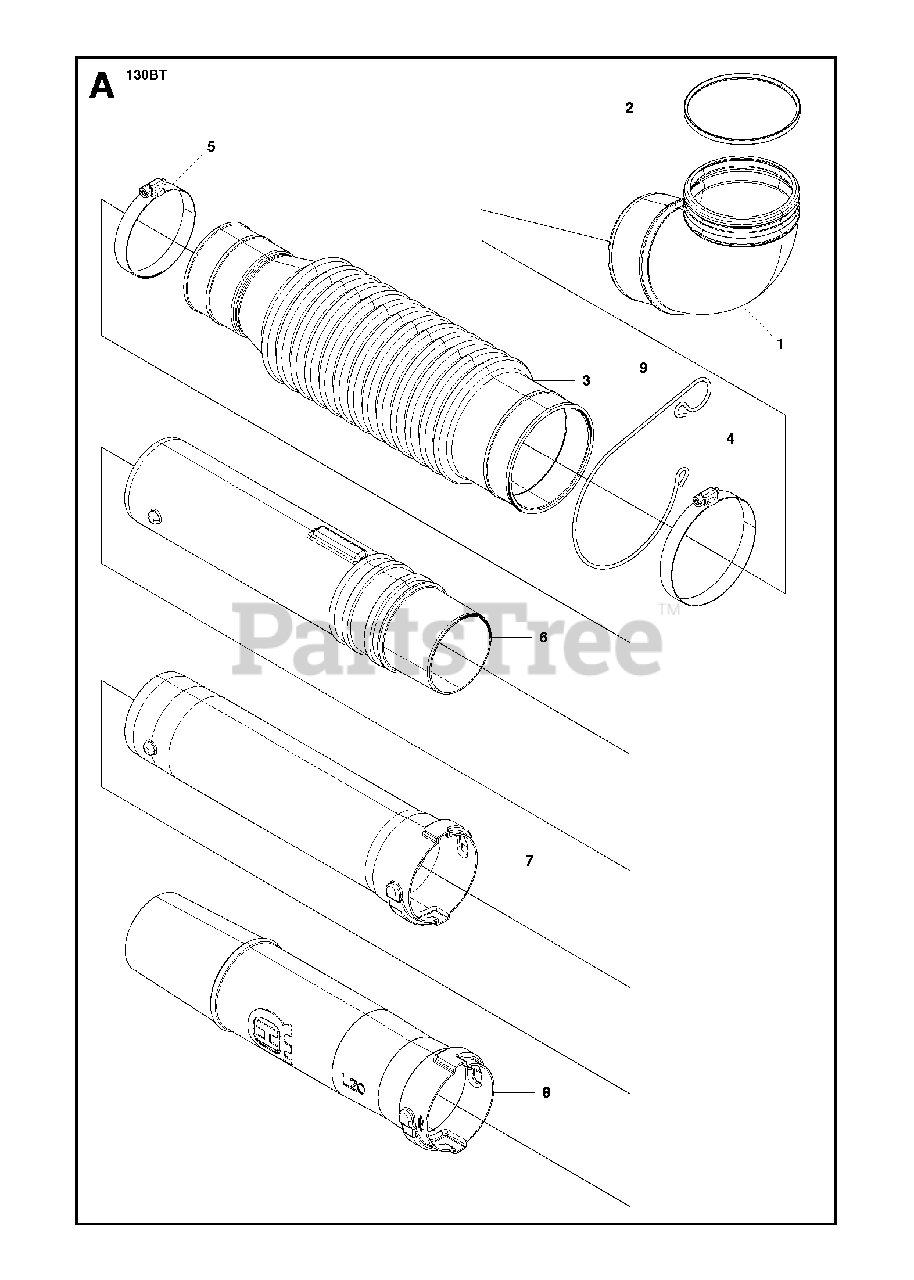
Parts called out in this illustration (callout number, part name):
4	CLAMP(F96)
6	TUBE SWIVEL JOINT
7	TUBE MIDDLE Z681151211
9	CLAMP CABLE
